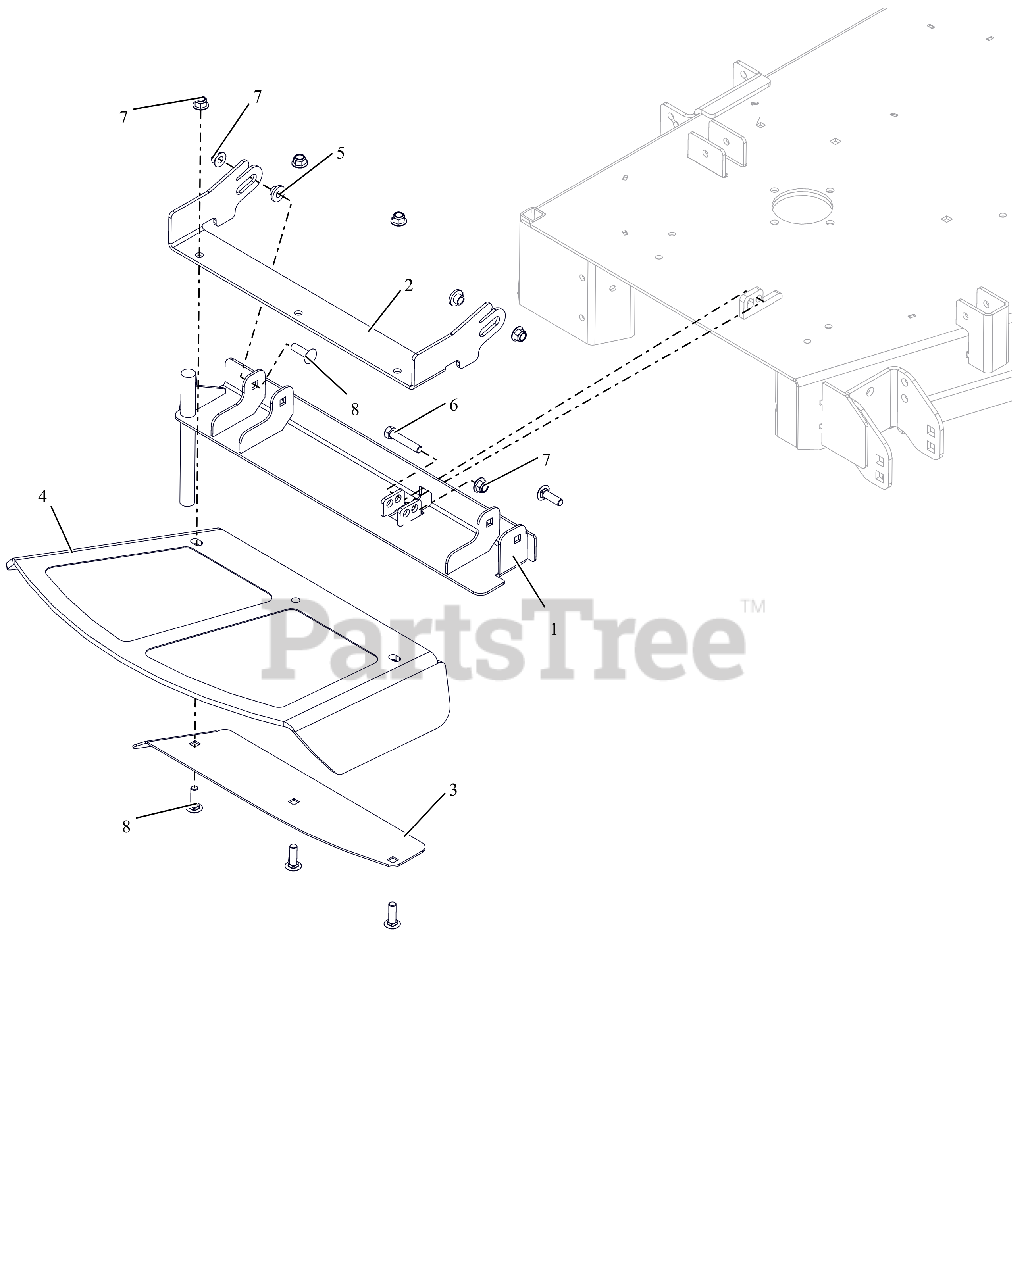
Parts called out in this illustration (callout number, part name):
1	48-60 DISCH CHT MTG WMT W/SAFE
2	48-60" CHUTE MTG BRKT - RED
3	48-60 DISCH CHUTE CLMP PLT-RED
4	CHUTE,48-60" FRMD RUBBER DISCH
5	BSHG-FLG .385X.500X.875X.406
6	BLT,HEX .38-16X2.00 G5 ZCC
7	NUT,NYL-FLG .38-16 GF ZCC
8	BLT,RHSSN .38-16X1.25 G5 ZCC
